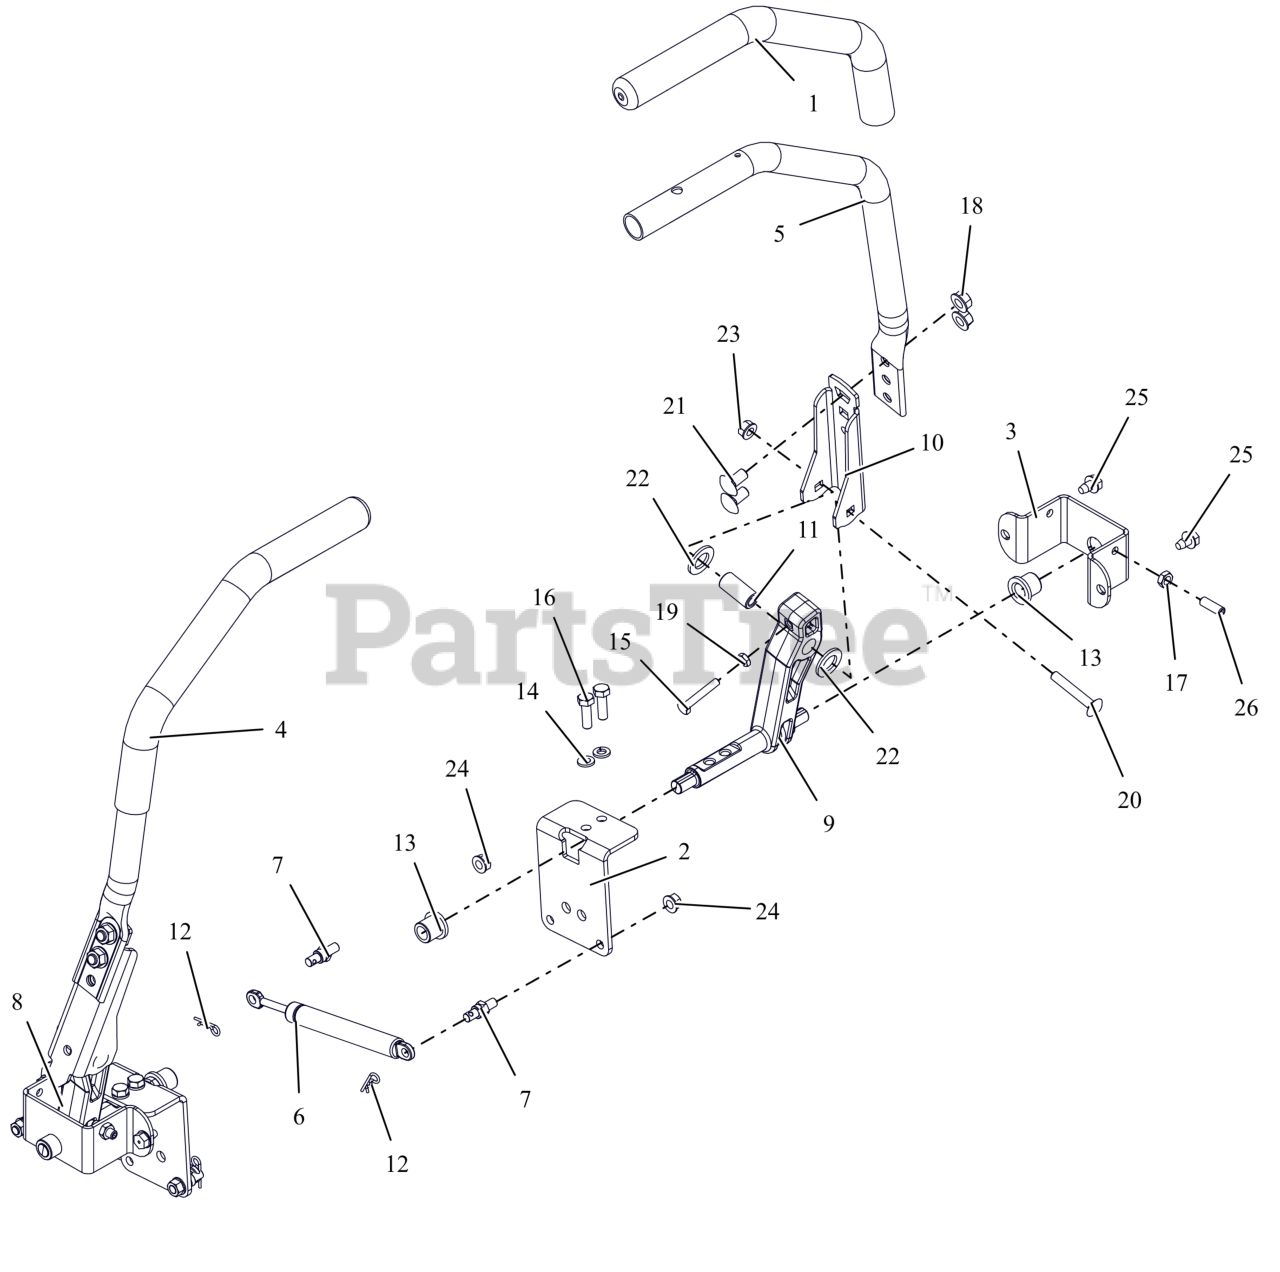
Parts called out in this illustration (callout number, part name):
1	GRIP, HANDLEBAR 15" FOAM
2	BRKT, STEEERING
3	BRKT, STEERING
4	HANDLE, STEERING-RH
5	HANDLE, STEERING-LH
6	DAMPER, STRAIGHT MOUNT
7	COUPLER, DAMPER MOUNT
8	STEERING, RH LWR CAST ARM
9	STEERING, LH LWR CAST ARM
10	ARM, CONTROL UPPER
11	BSHG-SLV .342 X .627 X 1.331
12	PIN, HAIR #213 .08X1.19 ZCC
13	BHSG-FLG .500X.750X.750X.125
14	WSHR,LK-REG .312X.078 ZCC
15	BLT, HEX .25-20X1.50F G5 ZCC
16	BLT, HEX .31-18X1.00 G8 ZCC
17	NUT-JAM .312-18 G2 ZCC
18	NUT-LK-CTR-FLG .375-16 GF ZCC
19	NUT-JAM .250-20 G2 ZCC
20	BLT, RHSSN .31-18X2.00 G5 ZCC
21	BTL,RHSSN .375-16 X 0.75 G5 FPB
22	WSHR, FRICTION
23	NUT,LK-CTR-FLG .31-18 GF ZCC
24	NUT-LK-TOP-FLG .312-18 GF ZCC
25	SCR,TAP .312-18X.50 HWH TR ZCC
26	SCR-SET, .312-18X1.000
